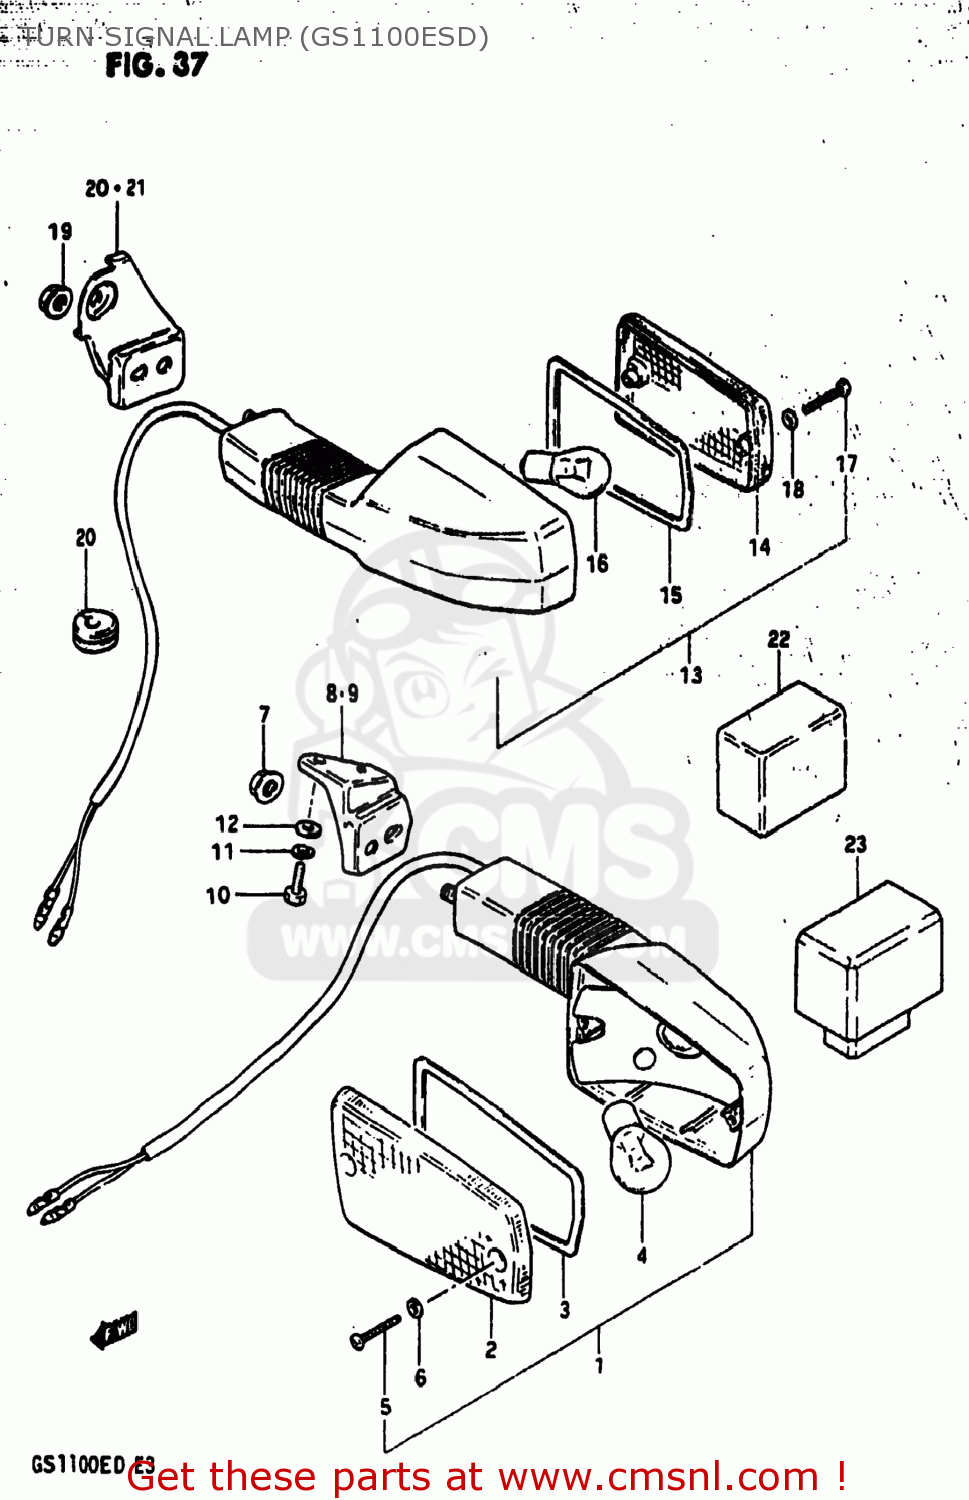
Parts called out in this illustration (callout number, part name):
1	LAMP ASSEMBLY,FRONT TURN SIGNAL
2	LENS,TURN SIGNAL LAMP
3	GASKET (NAS)
4	BULB 12V35/35W
5	SCREW
6	GASKET (NAS)
7	NUT
8	BRACKET,FRONT TURN SIGNAL
9	BRACKET,FRONT TURN SIGNAL
10	BOLT
11	LOCK WASHER
12	WASHER
13	LAMP ASSEMBLY,FRONT TURN SIGNAL
14	LENS
15	GASKET (NAS)
16	BULB(12V23W,STANLEY,A4577A)
17	SCREW
18	GASKET (NAS)
19	NUT
20	BRACKET,REAR TURN SIGNAL
21	BRACKET,REAR TURN SIGNAL
22	RELAY ASSY,TURNSIGNAL
23	UNIT,TURN SIGNAL CONTROL
